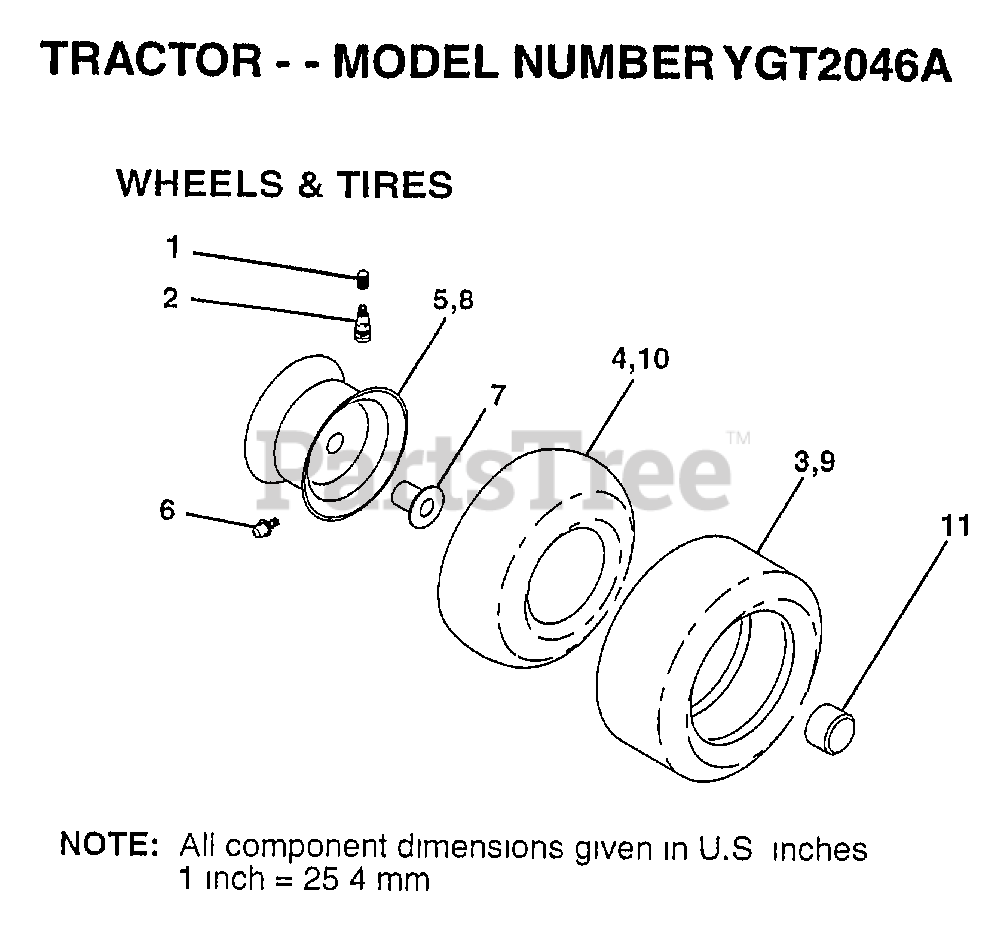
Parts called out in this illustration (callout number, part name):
1	VALVE CAP
2	VALVE STEM LT
4	TUBE.5.3/4.5/6
5	"RIM ASM 8"" FRT"
6	FITTING LT
7	"FLANGE, BEARING"
8	RIM ASM 12" REAR
10	TUBE.23X8/10-12
11	HUB CAP
